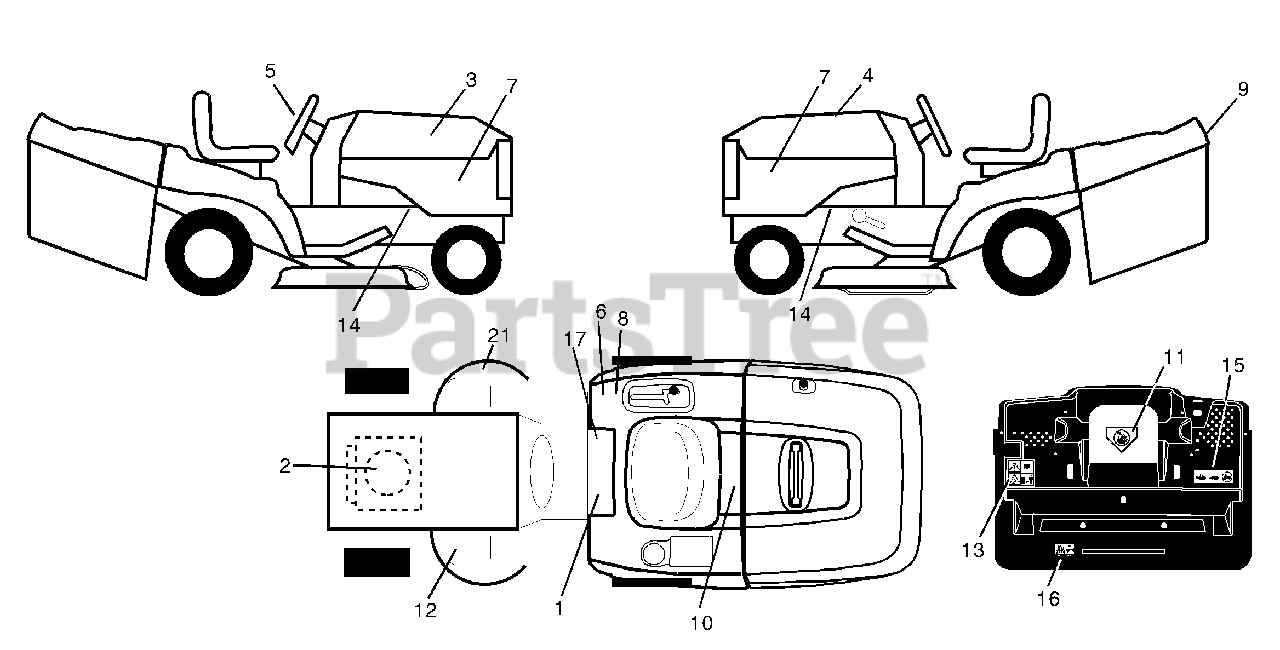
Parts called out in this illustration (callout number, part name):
1	Decal Read Owner's Manual Sym
2	Decal Hp Engine
3	Decal Hood Rh
4	Decal Hood Lh
5	Decal Wheel Logo
6	Decal 100 DBA
7	Decal Panel Side
8	Decal Europe Stand Ce
9	Decal Fender Logo
10	Decal Bat Dan/Poi P/L Sym Wpn
11	Decal Mower Cut Finger Symbol
12	Decal Brake/Clutch Symbol Lt
13	Decal Warn Back Plate CRD
14	Decal Chassis Hot Muffler
15	Decal Oper Bag Presence CRD
16	Decal Drawbar Load Limit
17	Decal Saddle Brake Parking
21	Decal Deck Sch 92 CRD
